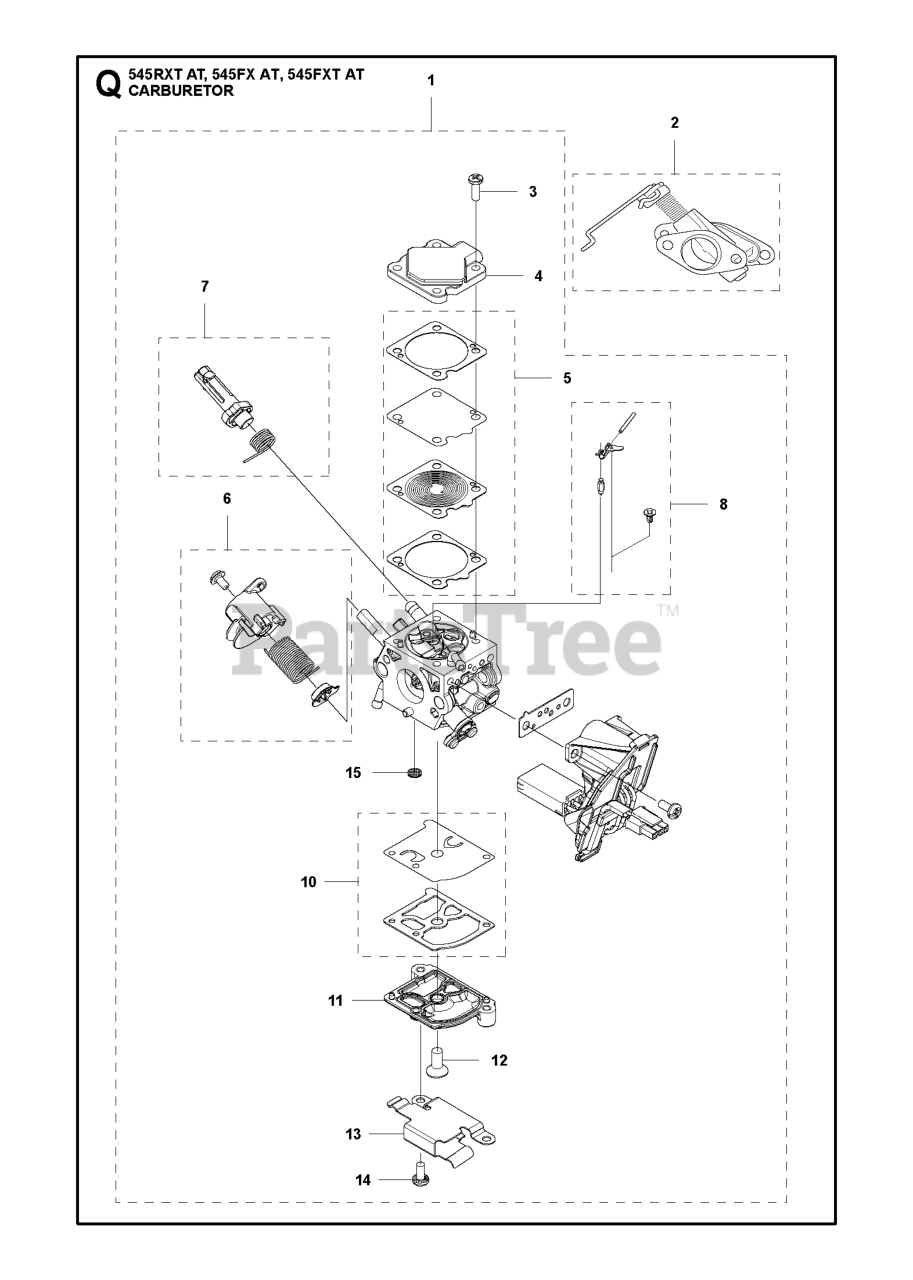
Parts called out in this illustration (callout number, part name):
1	CARBURETTOR AT-13 SPAREPART
2	HOUSING ASSY AIRHEAD
5	DIAPHRAGM & GASKET KIT AT SPIR
6	CARBURETTOR KIT THROTTLE
7	CARBURETTOR KIT CHOKE SPAREPAR
8	CARBURETTOR KIT METERING
10	CARBURETTOR KIT PUMP
13	BRACKET CONTACT
15	FUEL INLET SCREEN
